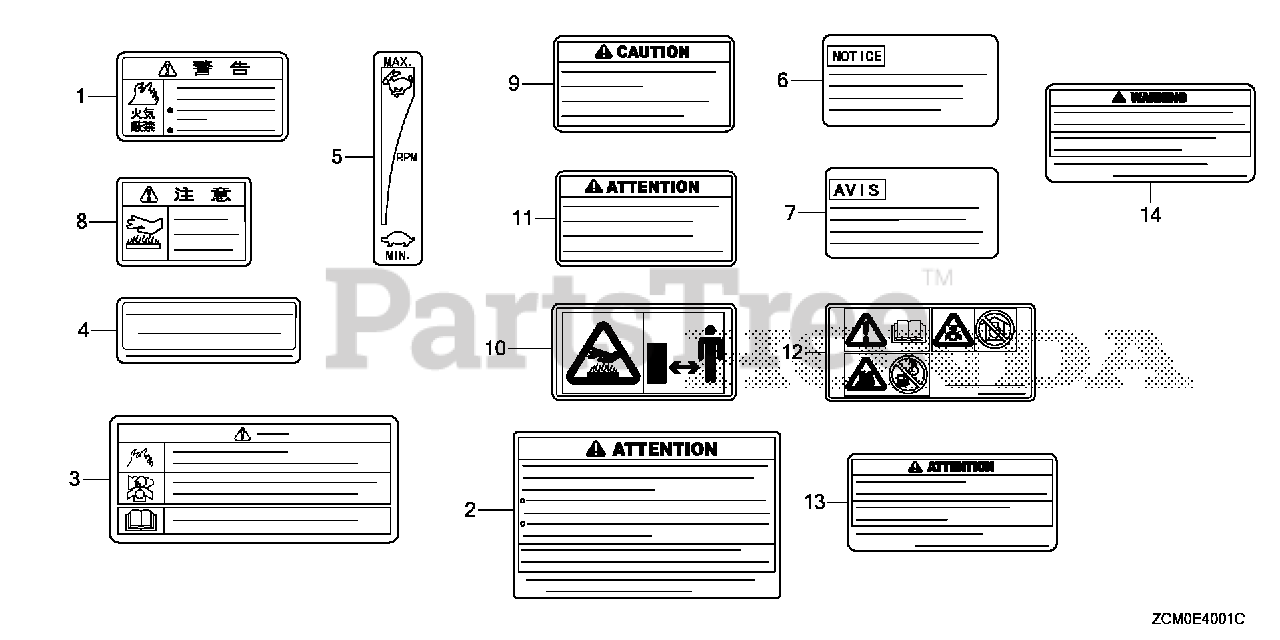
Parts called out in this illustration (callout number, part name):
2	MARK, OPERATOR CAUTION (FRENCH)
9	MARK, EX. CAUTION (ENGLISH)
11	MARK, EX. CAUTION (FRENCH)
